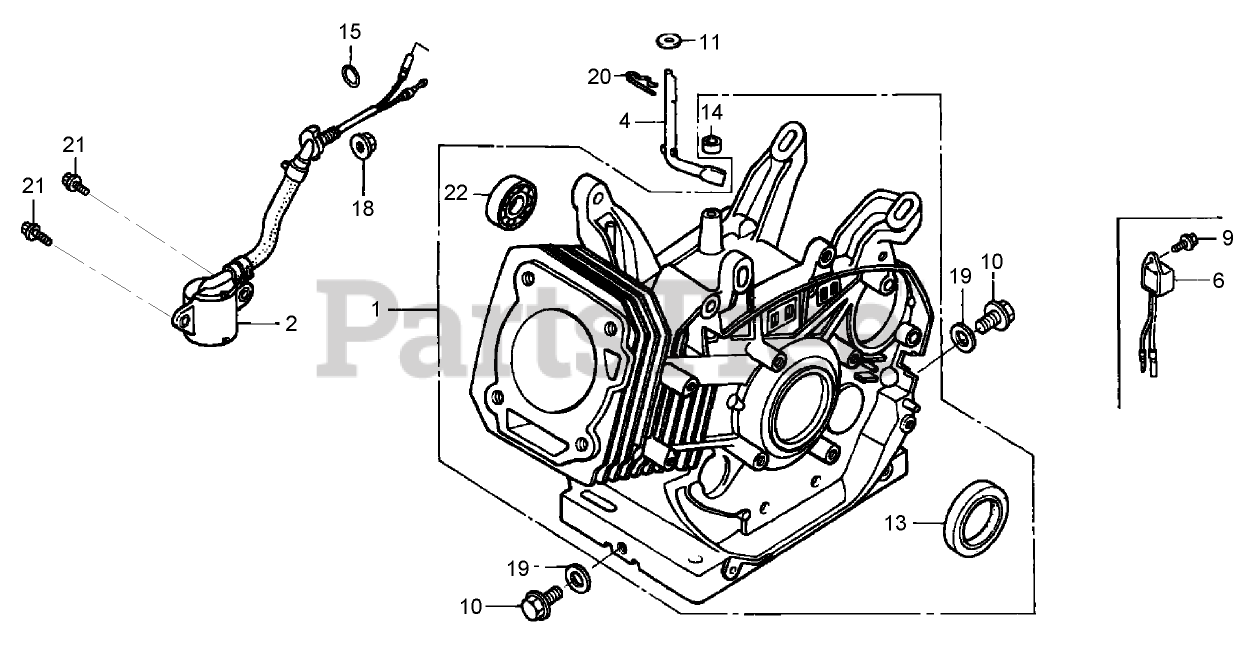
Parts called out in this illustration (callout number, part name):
1	CYLINDER ASM
2	SWITCH ASM-OIL LEVEL
4	SHAFT-GOVERNOR ARM
6	ALERT UNIT-OIL
9	BOLT-FLANGE (6X12) (C T200)
10	BOLT-DRAIN PLUG
11	WASHER
13	SEAL-OIL (35X5X8)
14	SEAL-OIL
15	O-RING
18	NUT-FLANGE
19	WASHER-DRAIN PLUG
20	PIN-LOCK
21	BOLT-FLANGE (6X12)
22	BEARING-RADIAL BALL
